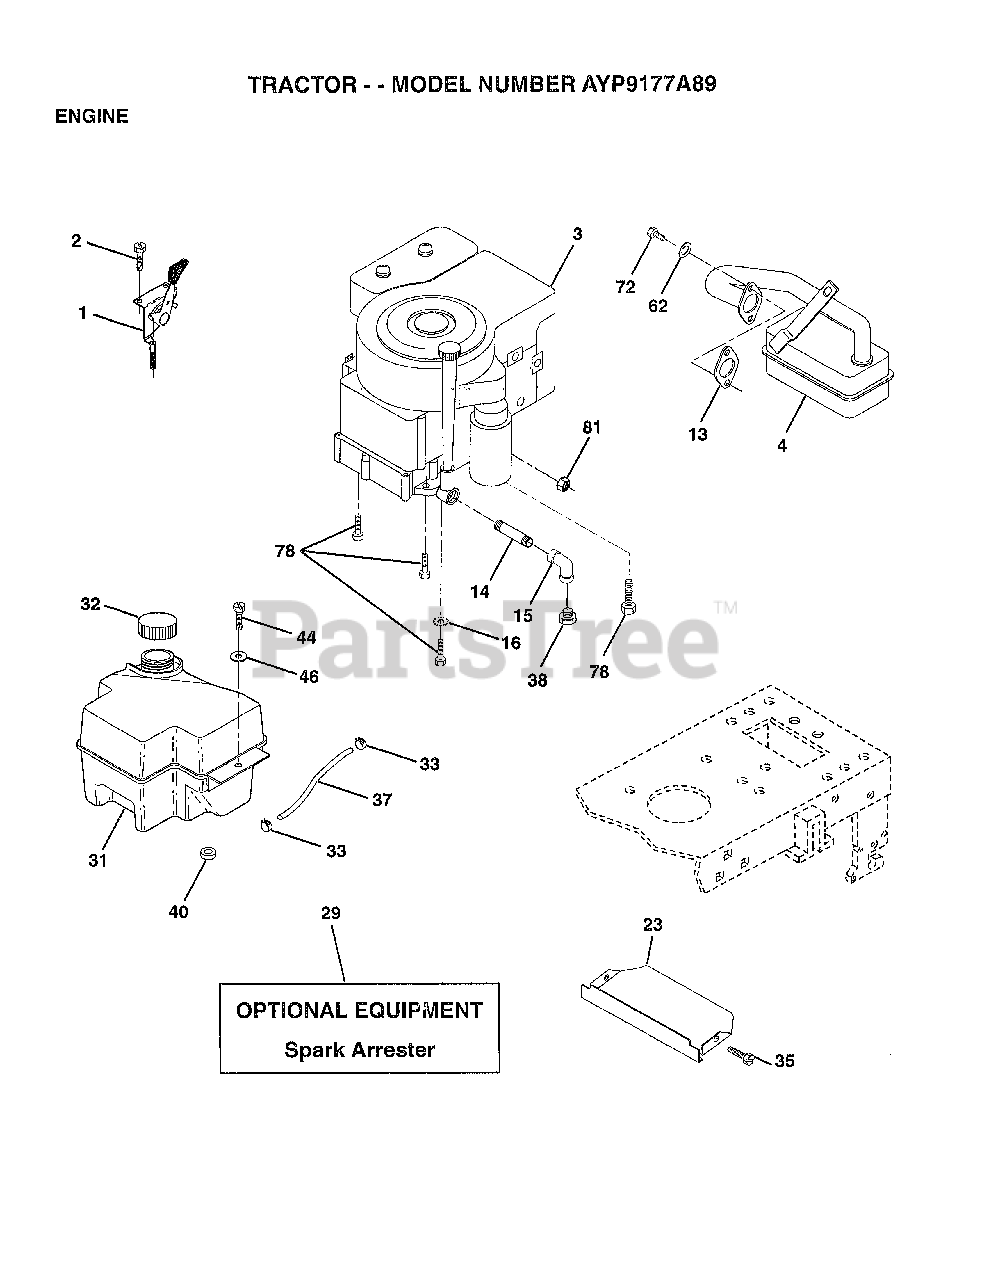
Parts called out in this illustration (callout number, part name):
1	CONTROL THROTTLE
2	SCREW LT
4	MUFFLER
13	GASKET ENG 1 313 LD TIN PLATED
14	PIPE NIPPLE
15	ELBOW
16	LOCKWASHER
23	SHIELD.BRN/DBR.GD
31	TANK.FUEL.FRONT.
32	CAP ASM FUEL
33	HOSE CLAMP
35	SCREW
37	LINE FUEL
44	SCREW HEX CRT
46	WASHER
62	LOCKWASHER
72	SCREW
78	SCREW
81	NUT
